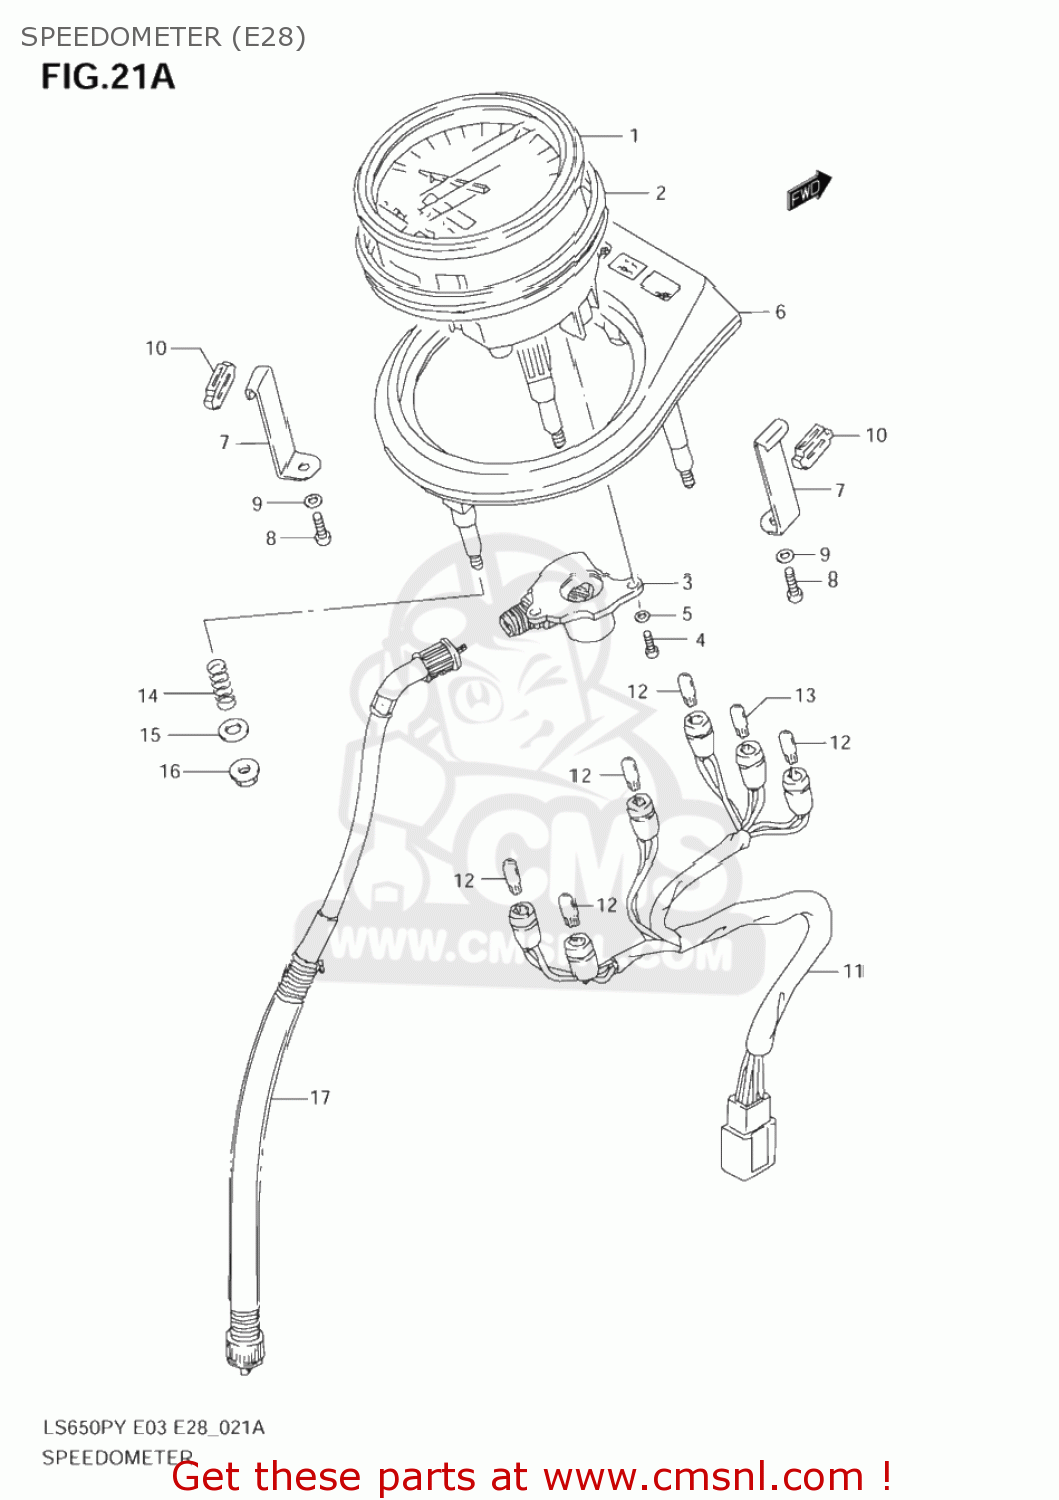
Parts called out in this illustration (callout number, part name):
1	SPEEDOMETER(KILO)
2	CUSHION,METER
3	BOX,GEAR
4	SCREW
5	WASHER,LOCK
6	HOOD,METER
7	BRACKET,METER
8	SCREW
9	WASHER,LOCK
10	CUSHION
11	SOCKET,METER
12	BULB(12V3W,T6.5)
13	BULB(12V1.7W,T6.5)
14	SPRING
15	WASHER(5.5X14X1.2)
16	NUT
17	CABLE ASSY,SPEEDOMETER
